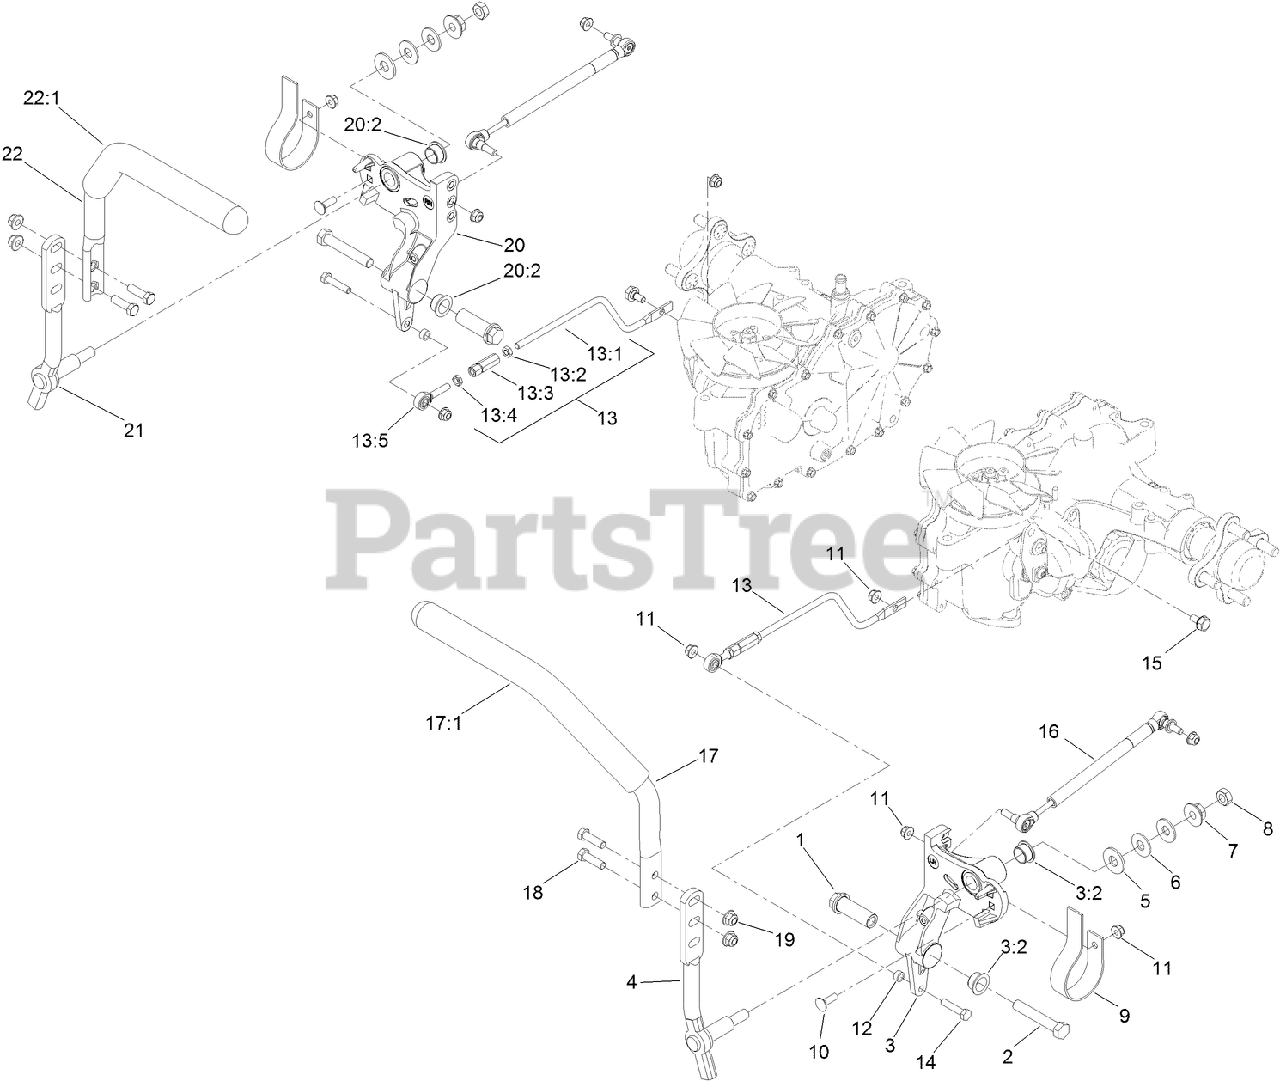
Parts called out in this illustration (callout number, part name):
1	HUB-THREADED
2	SCREW-HH
3	LH MOTION CONTROL AND BUSHING ASM
3:2	BUSHING-FLANGE
4	LEVER-CONTROL MOTION, LH
5	WASHER-FLAT
6	WASHER-SPRING
7	NUT-HF
8	NUT-JAM
9	SPRING-LEAF
10	BOLT-CARR
11	NUT-HF, NI
12	SPACER-YOKE, RIGHT
13	HYDRO CONTROL ROD ASM
13:1	ROD-CONTROL, HYDRO
13:2	NUT-JAM
13:3	NUT-ROD ADJUSTMENT
13:4	NUT-JAM
13:5	BEARING-ROD END, LH
14	SCREW-HH
15	BOLT-SHOULDER
16	DAMPER-CONTROL, MOTION
17	LH STEERING HANDLE ASM
17:1	GRIP-CONTROL, LEVER
18	SCREW-HH
19	NUT-HF, NI
20	RH MOTION CONTROL AND BUSHING ASM
20:2	BUSHING-FLANGE
21	LEVER-CONTROL MOTION, RH
22	RH STEERING HANDLE ASM
22:1	GRIP-CONTROL, LEVER
